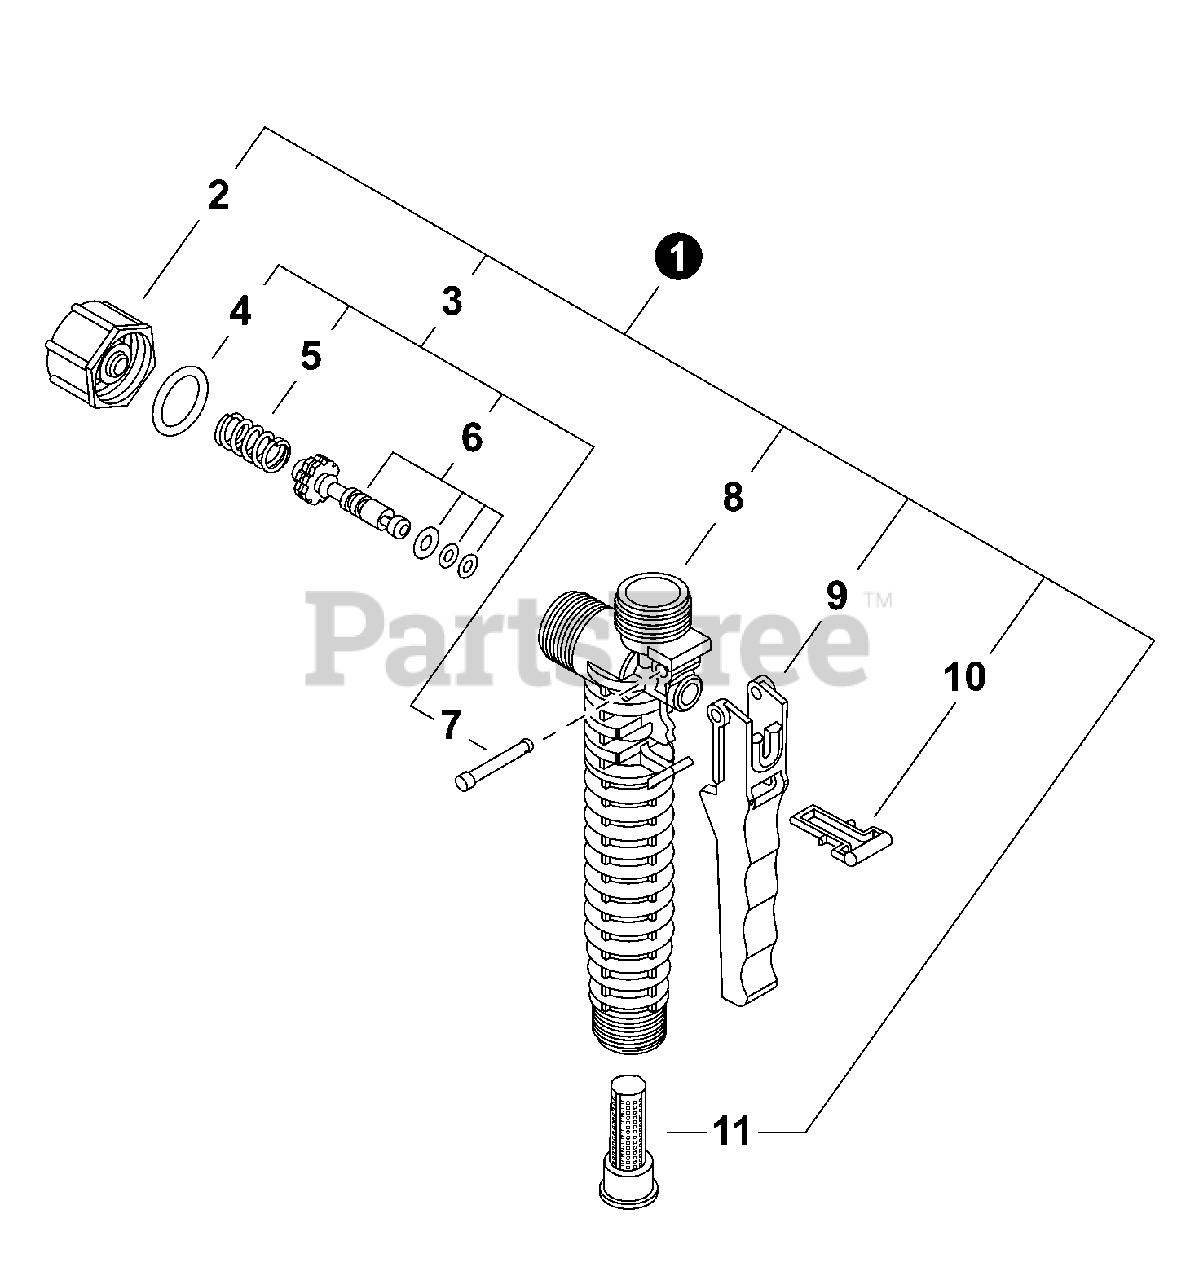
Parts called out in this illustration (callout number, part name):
1	GUN, SPRAY
2	CAP, DISCHARGE
3	REPAIR KIT, DISCHARGE
4	O-RING, DISCHARGE
5	SPRING, DISCHARGE
6	SPOOL ASSY
7	PIN, TRIGGER
8	BODY, SPRAY GUN
9	LEVER, TRIGGER
10	LOCK, TRIGGER
11	FILTER, SPRAY GUN
